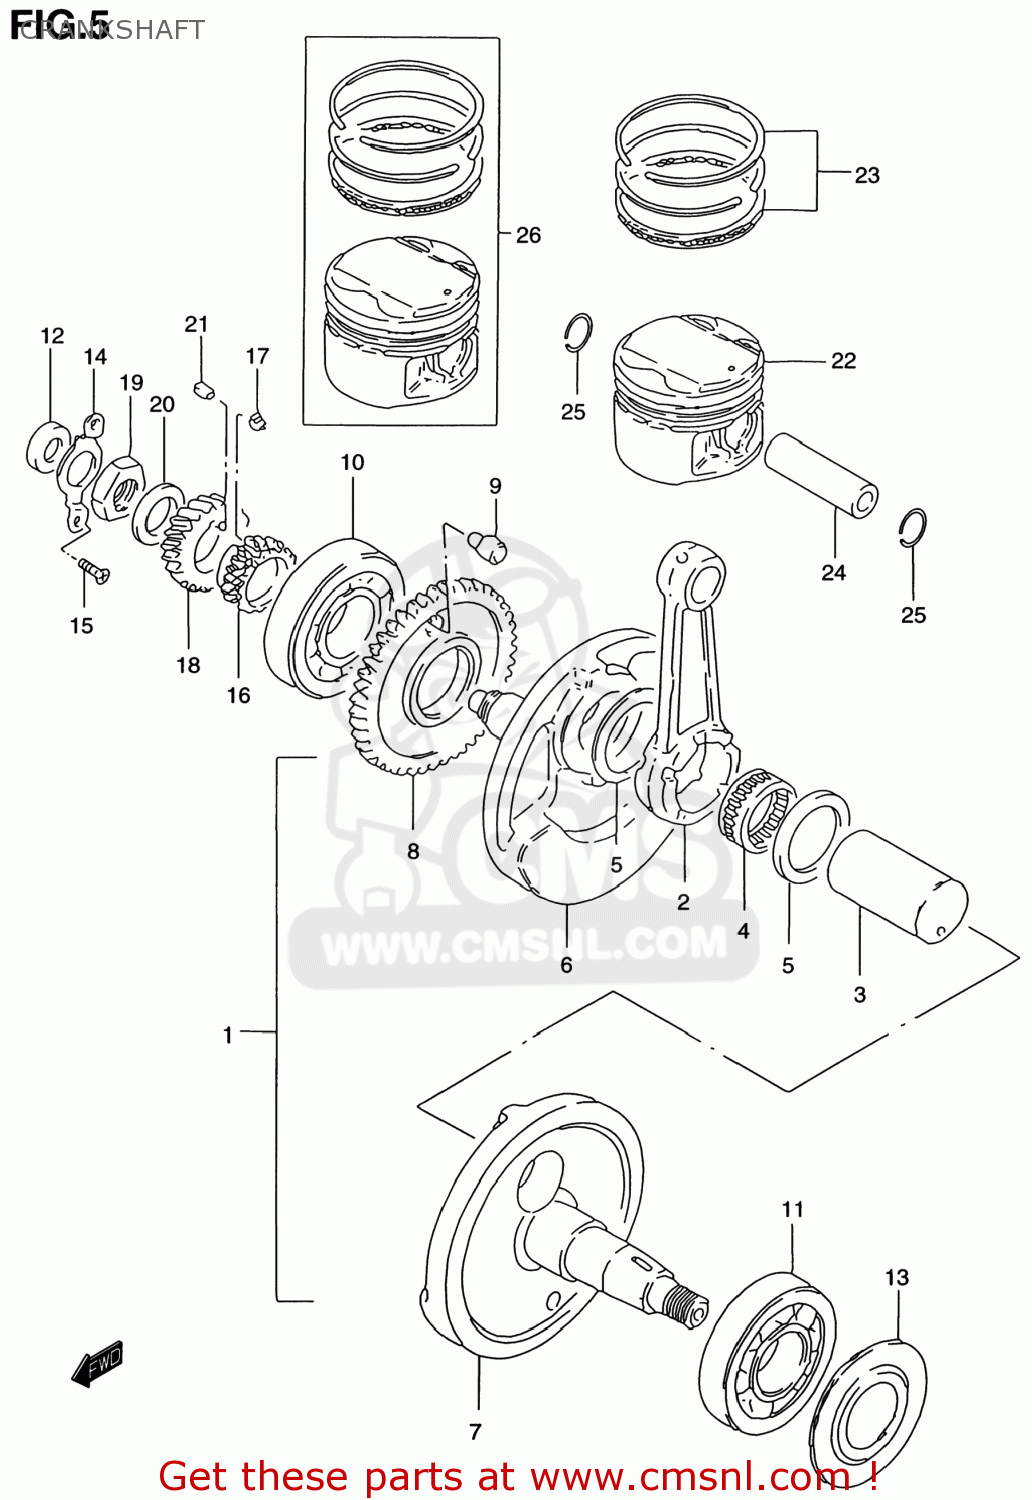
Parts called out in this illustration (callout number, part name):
1	CRANKSHAFT ASSEMBLY
2	ROD,CONNECTING
3	PIN,CRANK
4	BEARING(31X39X21)
5	WASHER(31X48.5X1)
6	CRANKSHAFT,R
7	CRANKSHAFT,LEFT
8	GEAR,CRANK BALANCER DRIVE
9	PIN
10	BEARING(30X72X19)
11	BEARING(35X80X21)
12	SEAL,OIL(14X26X6)
13	WASHER,CRANKSHAFT OIL SEALING
14	RETAINER,CRANKSHAFT BEARING,R
15	SCREW
16	SPROCKET,CAM CHAIN DRIVE(NT:21
17	KEY,SPROCKET
18	GEAR,PRIMARY DRIVE NO.21
19	NUT (20MM)
20	WASHER
21	KEY
22	PISTON
23	RING SET,PISTON
24	PIN,PISTON
25	CIRCLIP
26	PISTON SET(OS:0.5)
